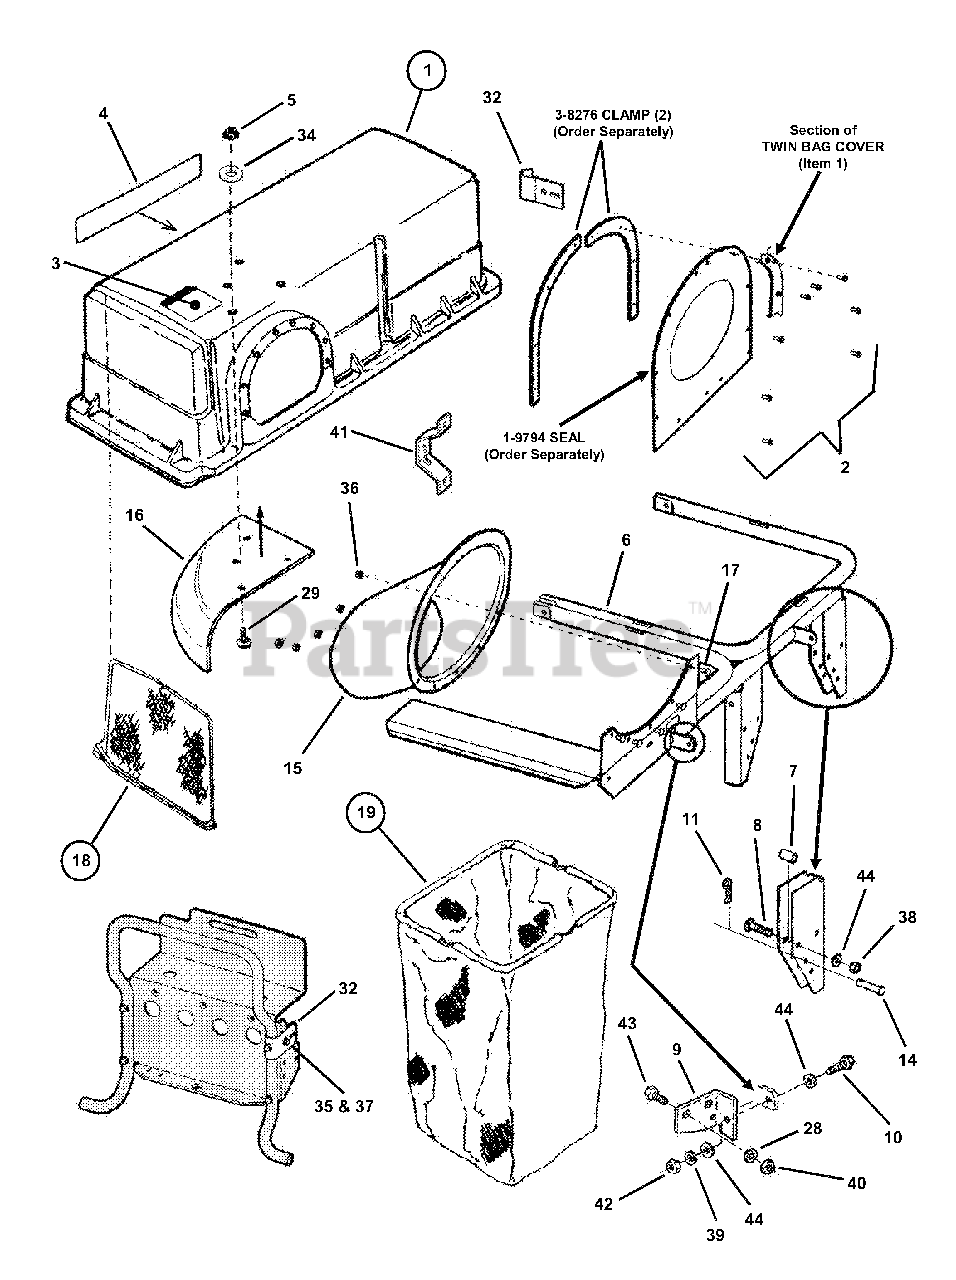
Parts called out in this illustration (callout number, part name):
1	ASS'Y, Cover
2	SCREW, #10-24 x 1/2" Self-Tap
3	DECAL, Warning
4	DECAL, Snapper
5	NUT, 1/4-20 Hex
6	WELDMENT, Frame
7	PAD, Bumper Mount
8	BOLT, 5/16-18 x 1-1/2" Carr.
9	HINGE, Top
10	SCREW, 5/16-24 x 1"
11	PIN, 3/32 x 1-1/2" Hair
14	PIN, 5/16 x 1-11/16" Clevis
15	INLET, Twin Bagger
16	SECTOR
17	BOLT, 1/4-20 x 1/2" Carriage
18	ASS'Y, Screen (w/indented items)
19	ASS'Y, Bag (w/indented items)
28	WASHER, 1/4" Lock
29	BOLT, 1/4-20 x 3/4" Carriage
32	SUPPORT, Bumper
34	WASHER, 1/4" Flat
35	SCREW, 5/16-18 x 3/4" Hex
36	NUT, 1/4-20 Hex Fl. Top Lock
37	NUT, 5/16-18 Hex Flange Lock
38	NUT, 5/16-18 Hex Center Lock
39	WASHER, 5/16" Split Lock
40	NUT, 1/4-28 Hex
41	BRACE, Twin Bag Catcher
42	NUT, 5/16-24 Hex Center Lock
43	SCREW, 1/4-28 x 3/4" Hex
44	WASHER, 5/16" Flat
